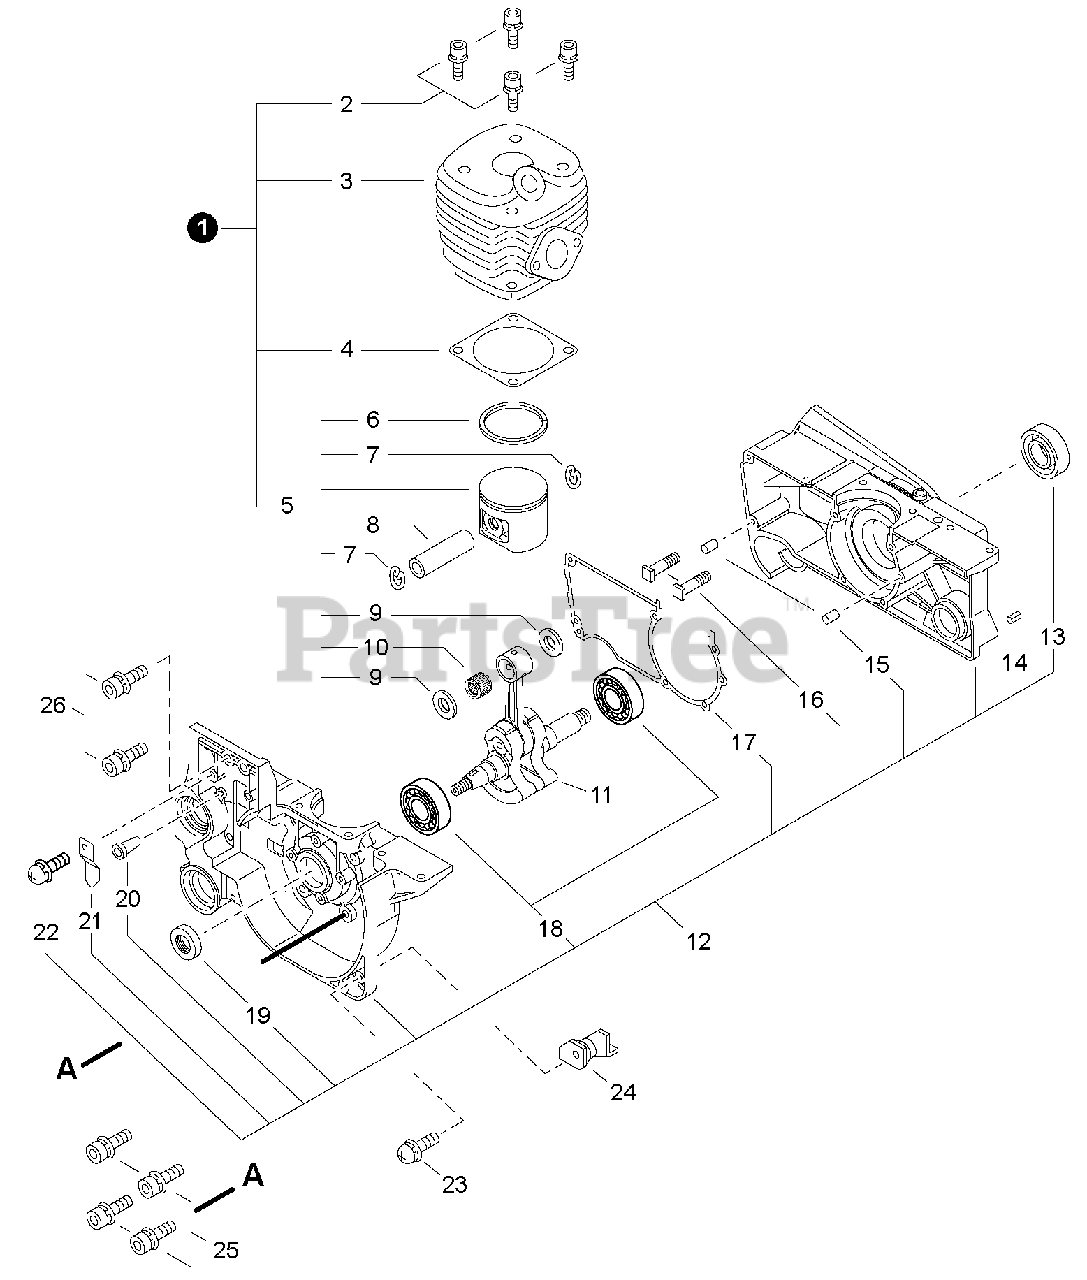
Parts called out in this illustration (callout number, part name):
1	REPAIR KIT, ENGINE
2	BOLT 5×25
3	CYLINDER
4	GASKET, CYLINDER
5	PISTON KIT
6	RING, PISTON
7	RING, SNAP
8	PIN, PISTON 12
9	WASHER, THRUST
10	BEARING, NEEDLE
11	CRANKSHAFT ASSY
12	CRANKCASE KIT
13	SEAL, OIL
14	PIN, SPRING Ø5×25 MM
15	PIN, LOCATING 5×10
16	STUD, GUIDE BAR 8
17	GASKET, CRANKCASE
18	BEARING, BALL 6202
19	SEAL, OIL
20	VENT ASSY
21	PLATE, EYE
22	SCREW 4×8
23	SCREW 5×14
24	CUSHION 5
25	BOLT M5×35
26	BOLT 5×20
